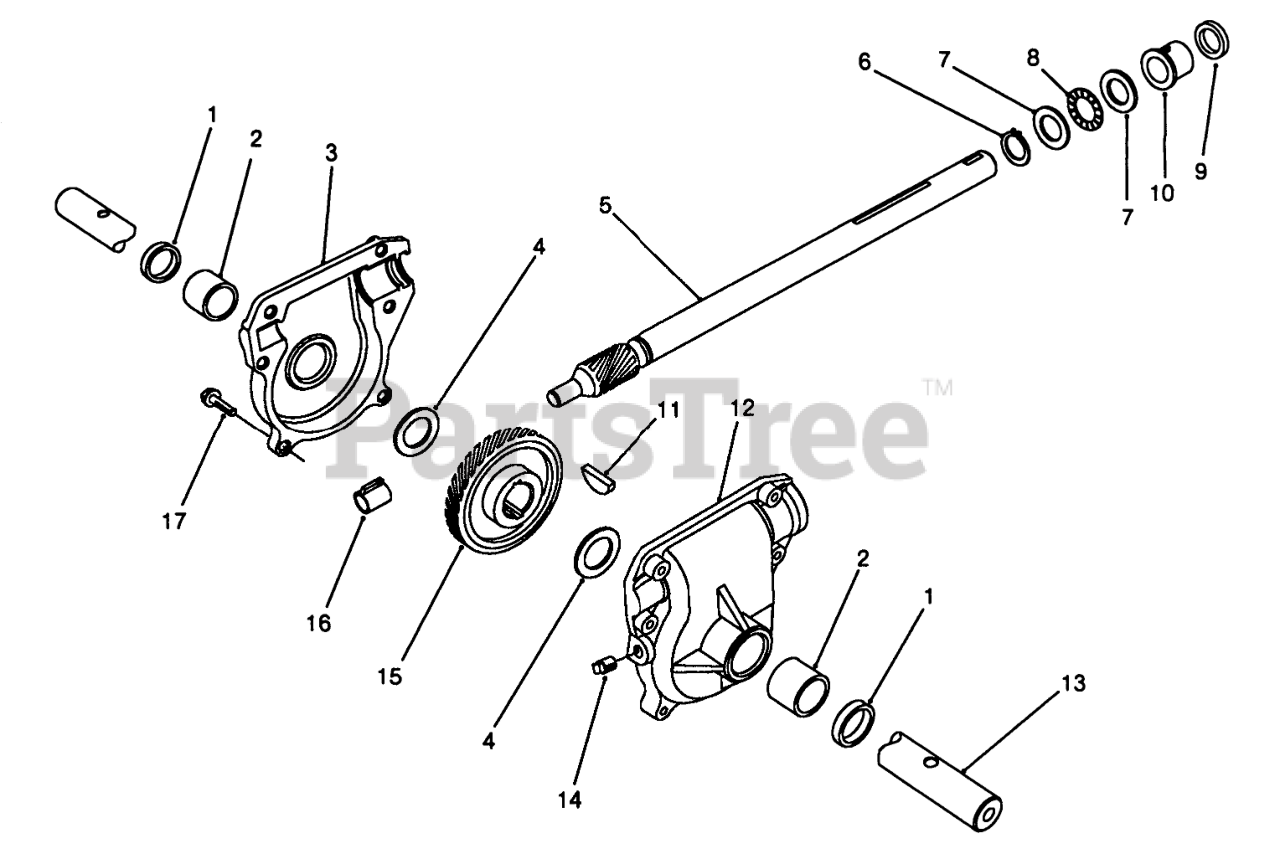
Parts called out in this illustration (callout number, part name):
1	SEAL-OIL
2	BUSHING
3	Gearcase Assembly-R.H. (Incl. Ref. #1-2)
4	WASHER-THRUST
5	Shaft-Impeller
6	RING-RETAINING, Ext
7	WASHER-THRUST
8	BEARING-THRUST
9	SEAL-OIL
10	BUSHING-INPUT
11	KEY-WOODRUFF
12	Gearcase Assembly-L.H. (Incl. Ref. #1-2)
13	SHAFT-AUGER
14	PLUG-PIPE, SQH
15	GEAR-HELICAL
16	BUSHING-WORM
